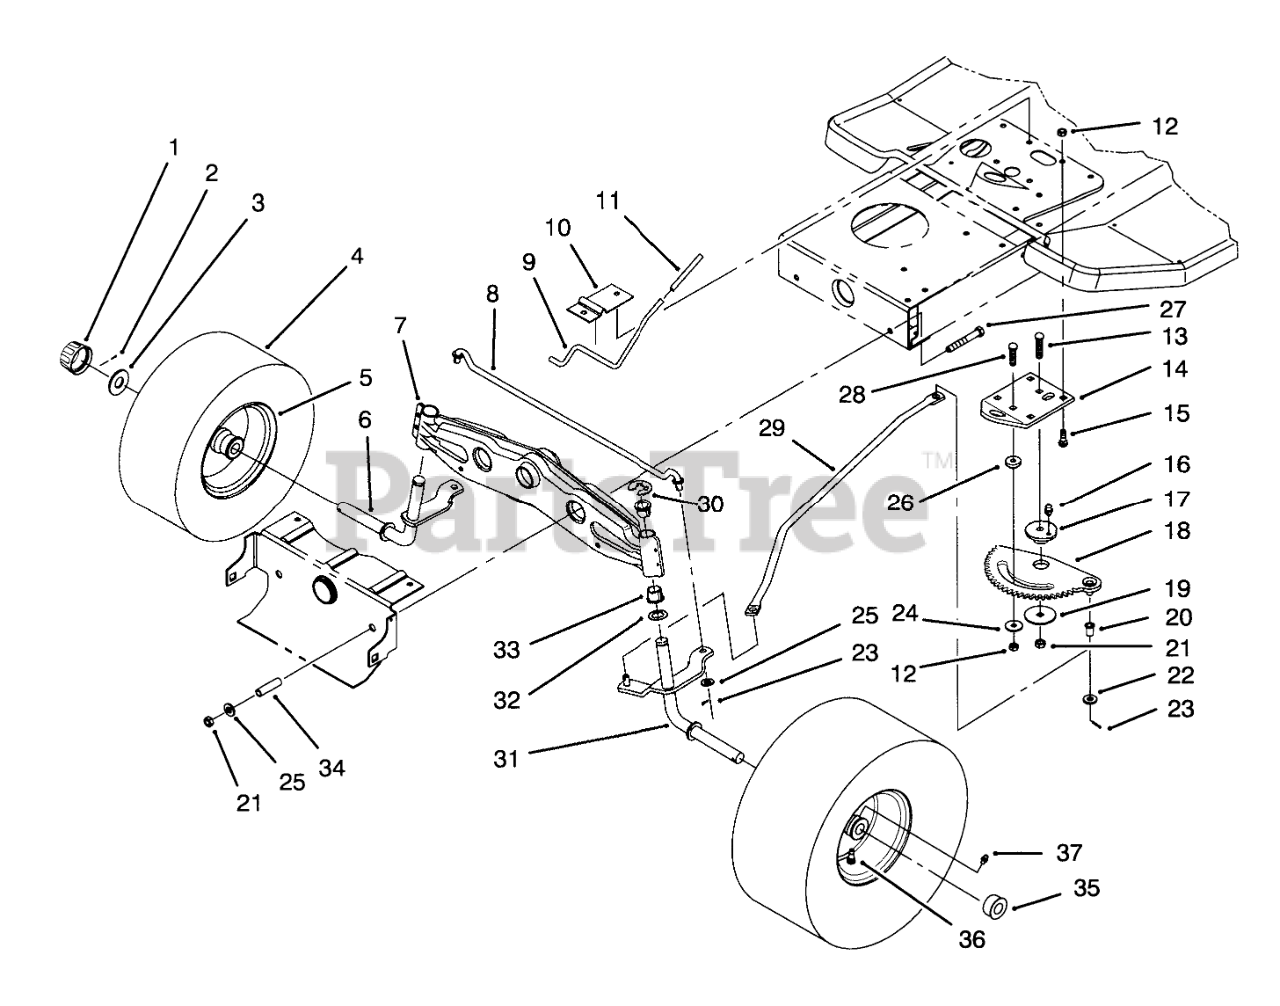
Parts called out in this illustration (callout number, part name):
1	CAP-HUB
2	PIN-COTTER
3	WASHER-PLAIN
4	TIRE 15 X 6.00 X 6
5	RIM ASM
6	Spindle-R.H.
7	Axle-Front
8	TIE ROD-STEERING
9	ROD-BRAKE, PARKING
10	Bracket-Parking Brake
11	GRIP-BRAKE, PARKING
12	NUT-LOCK, NI
13	SCREW-CARR
14	Bracket-Steering Rack
15	BOLT-CARR
16	FITTING-GREASE
17	BUSHING-ECCENTRIC
18	RACK-STEERING
19	WASHER-BEARING
20	BUSHING-FLANGED, NYLON
21	NUT-LOCK, NI
22	WASHER-FLAT
23	PIN-COTTER
24	WASHER-PIVOT
25	WASHER-FLAT
26	SPACER-RACK, STEERING
27	SCREW-HH
28	SCREW-CARR
29	LINK-DRAG
30	E-RING
31	Spindle-L.H.
32	WASHER-THRUST
33	BUSHING
34	SPACER
35	BEARING-WHEEL
36	STEM-VALVE
37	FITTING-GREASE
